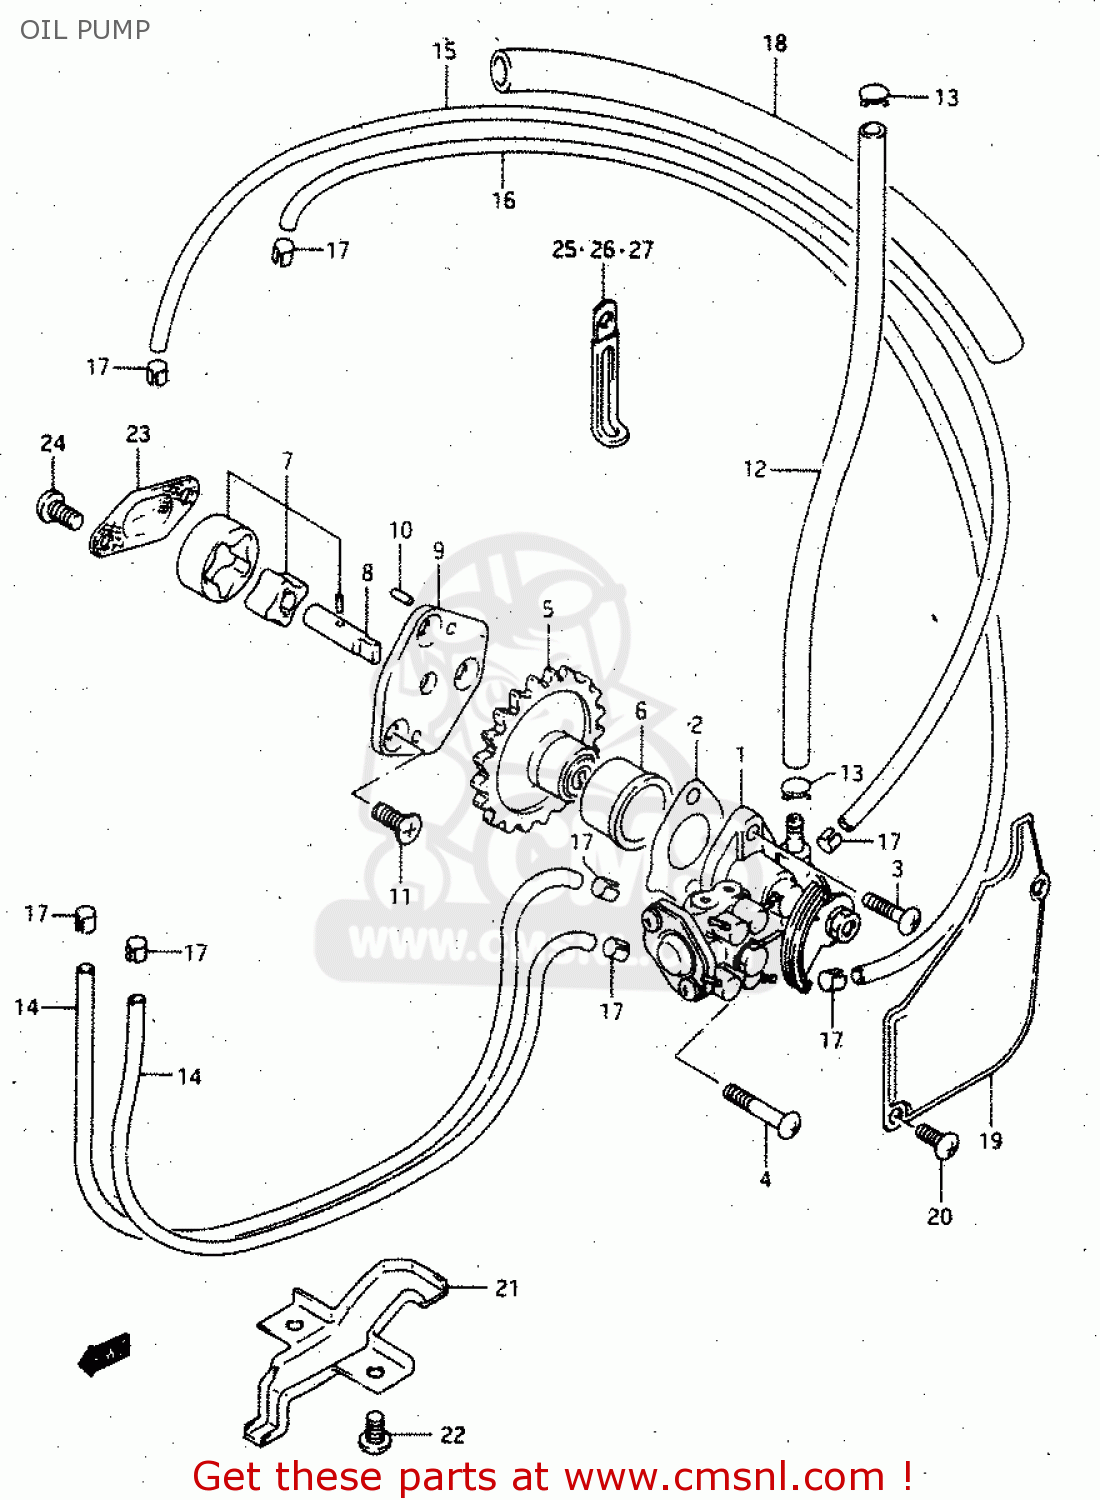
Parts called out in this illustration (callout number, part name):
1	PUMP ASSY,OIL
2	GASKET,OIL PUMP (NAS)
3	SCREW
4	SCREW
5	GEAR,OIL PUMP DRIVE(NT:21)
6	BUSH
7	ROTOR SET,OIL PUMP
8	SHAFT,OIL PUMP ROTOR DRIVE
9	COVER,OIL PUMP
10	PIN
11	SCREW
12	HOSE (4.5X8.5X600)
13	CLIP
14	HOSE(2X5X600)
15	HOSE(2X5X2000)
16	HOSE(2X5X600)
17	CLIP
18	HOSE(11X15X600)
19	CAP,OIL PUMP INSPECTION
20	SCREW
21	COVER,OIL HOSE
22	SCREW
23	STRAINER,ENGINE OIL
24	BOLT
25	CLAMP
26	CLAMP(L:45 T:0.6)
27	CLAMP(L:65 T:0.8)
